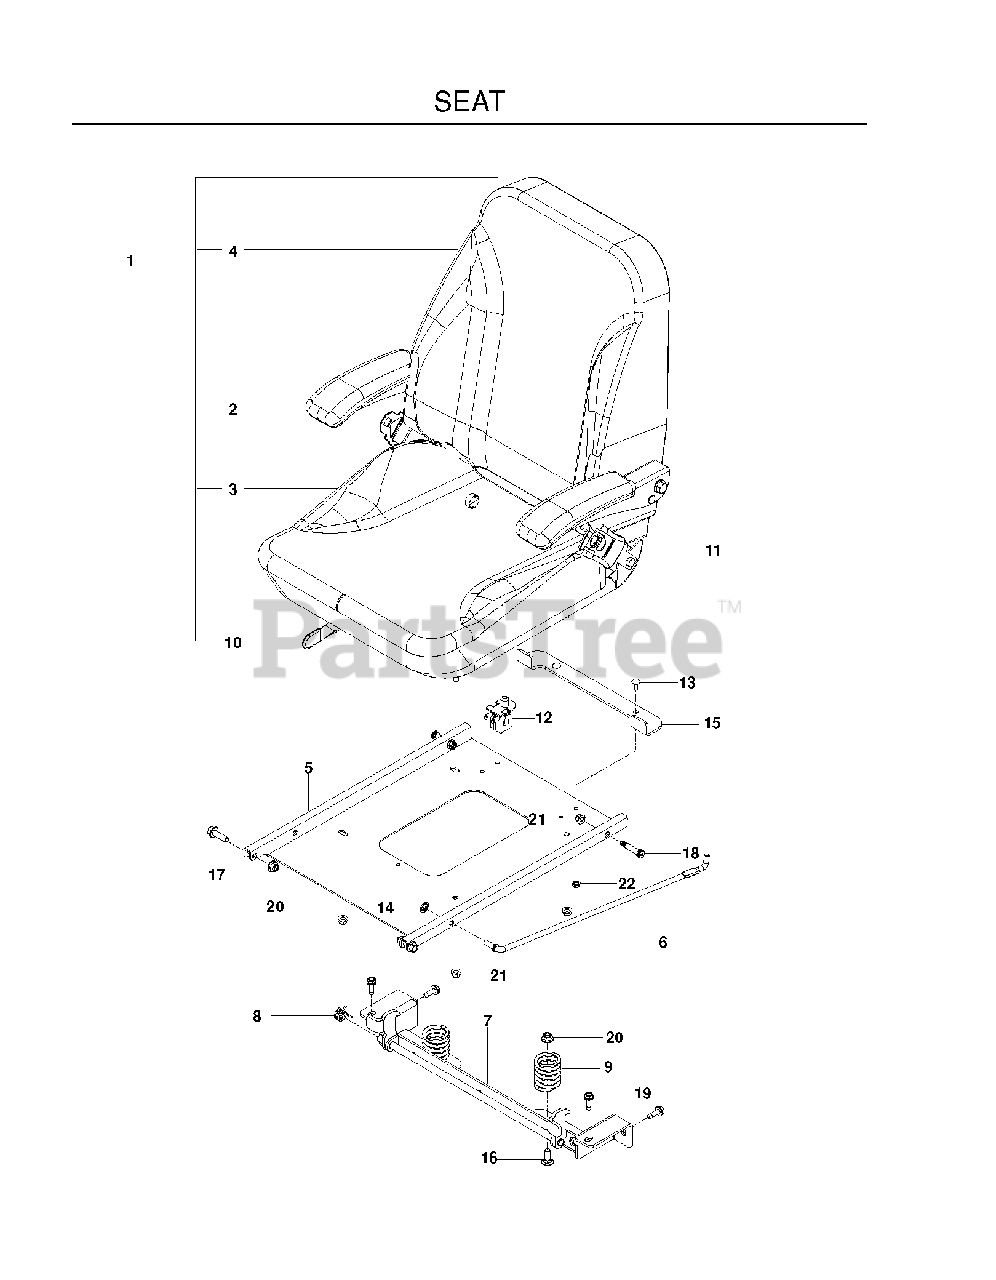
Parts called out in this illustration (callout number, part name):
1	SEAT ASSY
2	ARMREST, RT
3	CUSHION COVER
4	BACK COVER
5	PAN, SEAT, BLACK
6	ROD, SEAT
7	LATCH, SEAT, BLK
8	SPRING, TORSION
9	SPRING, SEAT
10	TRACK KIT
12	SEAT SWITCH
14	BOLT RETAINER 3/8
15	RHSSNB, 1/4-20X5/8
16	RHSNB 3/8C X 1
17	HHFS 3/8-16 X 1.25 GD 5
18	BOLT, SHOULDER 3/8 X 1.25
19	BLT 5/16-18 X 1 THRD FORM ZD
20	NUT 3/8-16 HEX FLG NYLOC ZD
21	5/16-18 NYLOC FLANGE NUT
22	JAM NUT 1/4C
